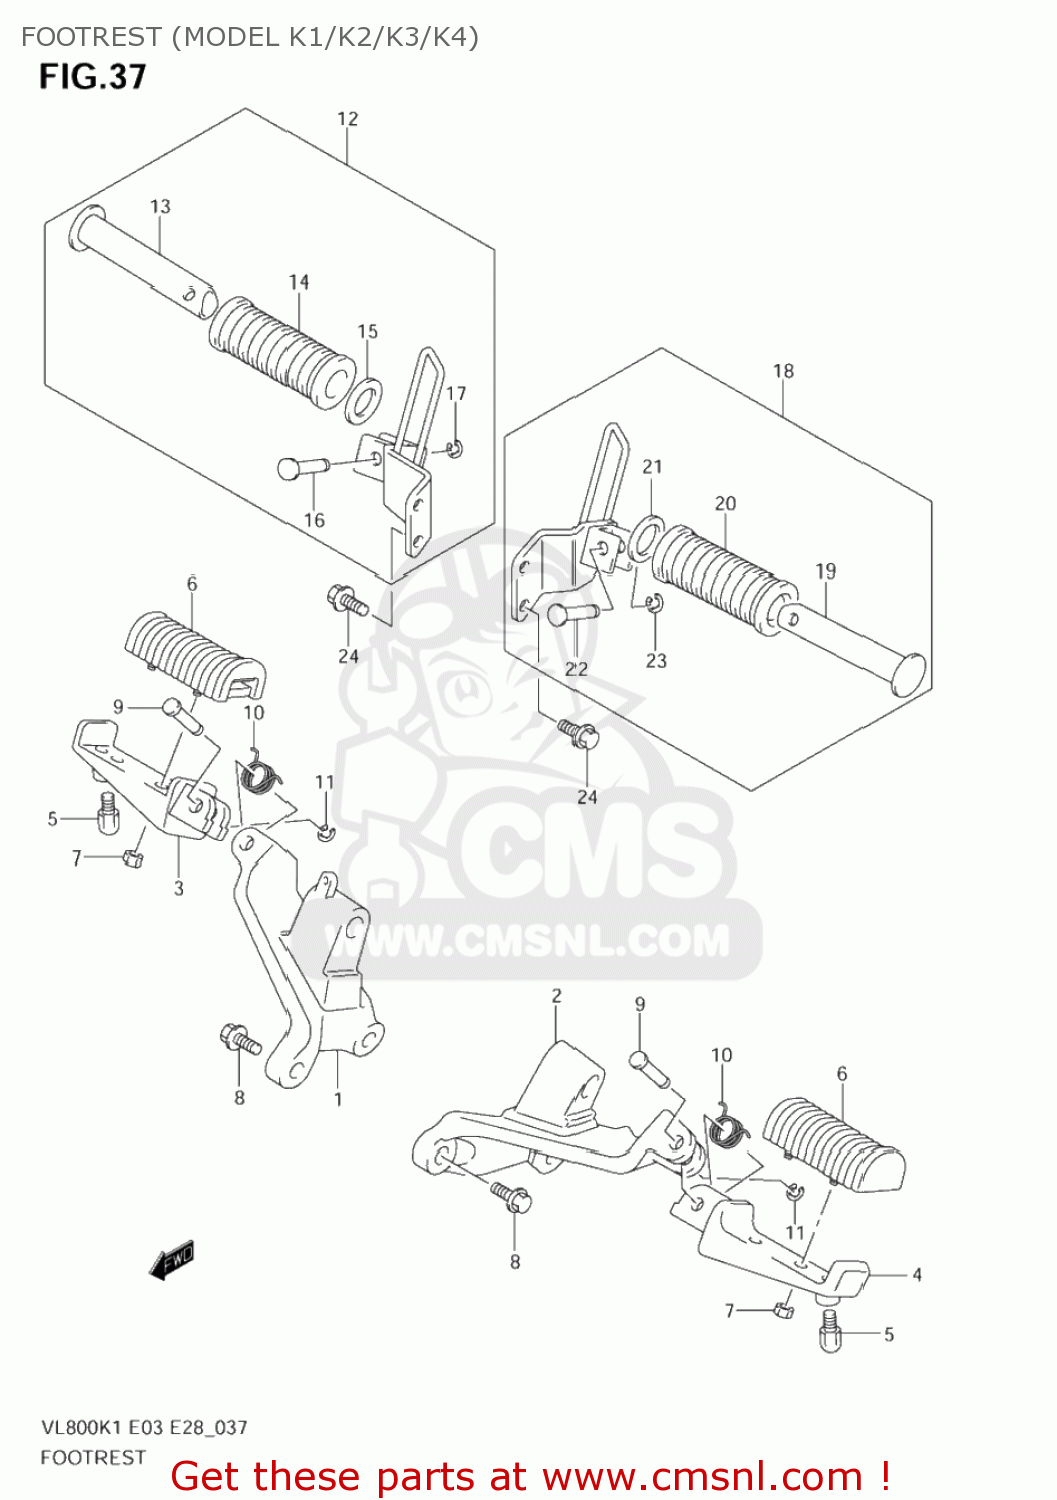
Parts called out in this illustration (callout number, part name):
1	BRACKET,FR FOOTREST,R
2	BRACKET,FRONT
3	BAR,FRONT FOOT
4	BAR,FRONT FOOT
5	BOLT,BANK SENSOR
6	RUBBER,FR FOOTREST
7	NUT
8	BOLT
9	PIN(8X33.2)
10	SPRING
11	E.RING
12	FOOTREST ASSY,PILLION,R
13	BAR,FOOTREST RUBBER
14	RUBBER,PILLION FOOTREST
15	WASHER(19.5X32X2)
16	PIN,PILLION FOOTREST
17	E-RING
18	FOOTREST ASSY,PILLION,L
19	BAR,FOOTREST RUBBER
20	RUBBER,PILLION FOOTREST
21	WASHER(19.5X32X2)
22	PIN,PILLION FOOTREST
23	E-RING
24	BOLT
